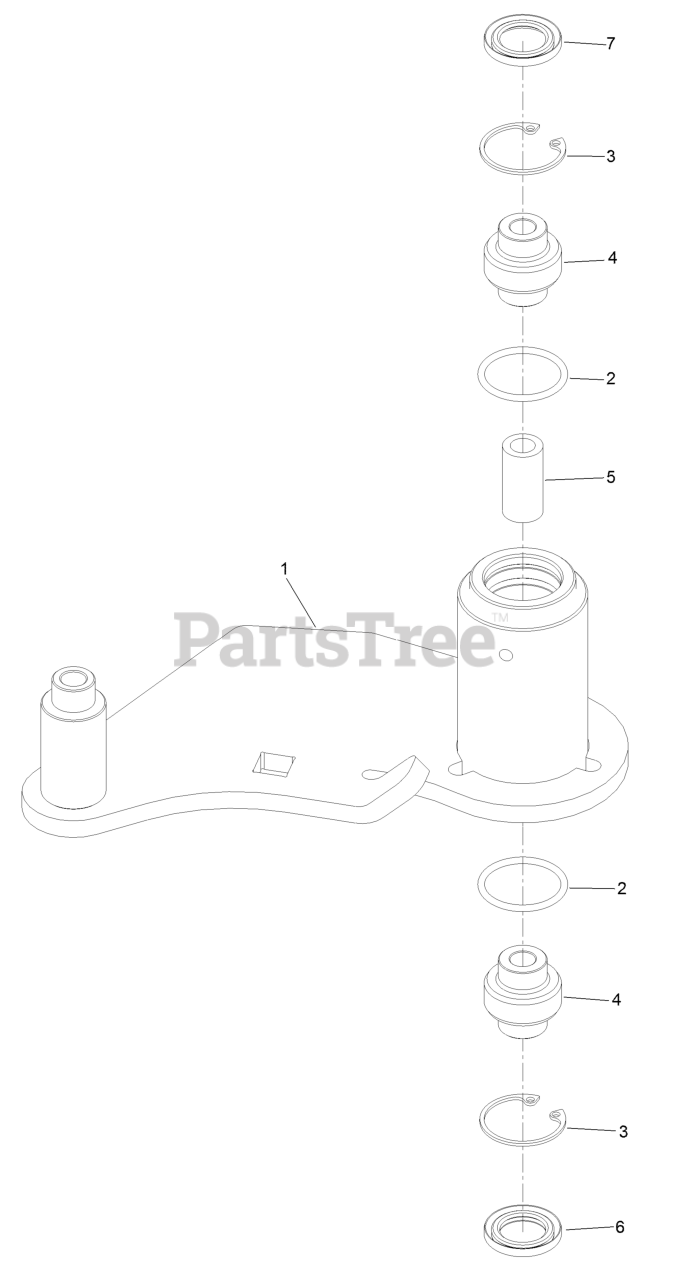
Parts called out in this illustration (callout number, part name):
1	Idler-Deck
3	RING-SNAP
4	BEARING-SPHERICAL
6	SEAL-LIP, DOUBLE
7	SEAL-LIP, SINGLE
